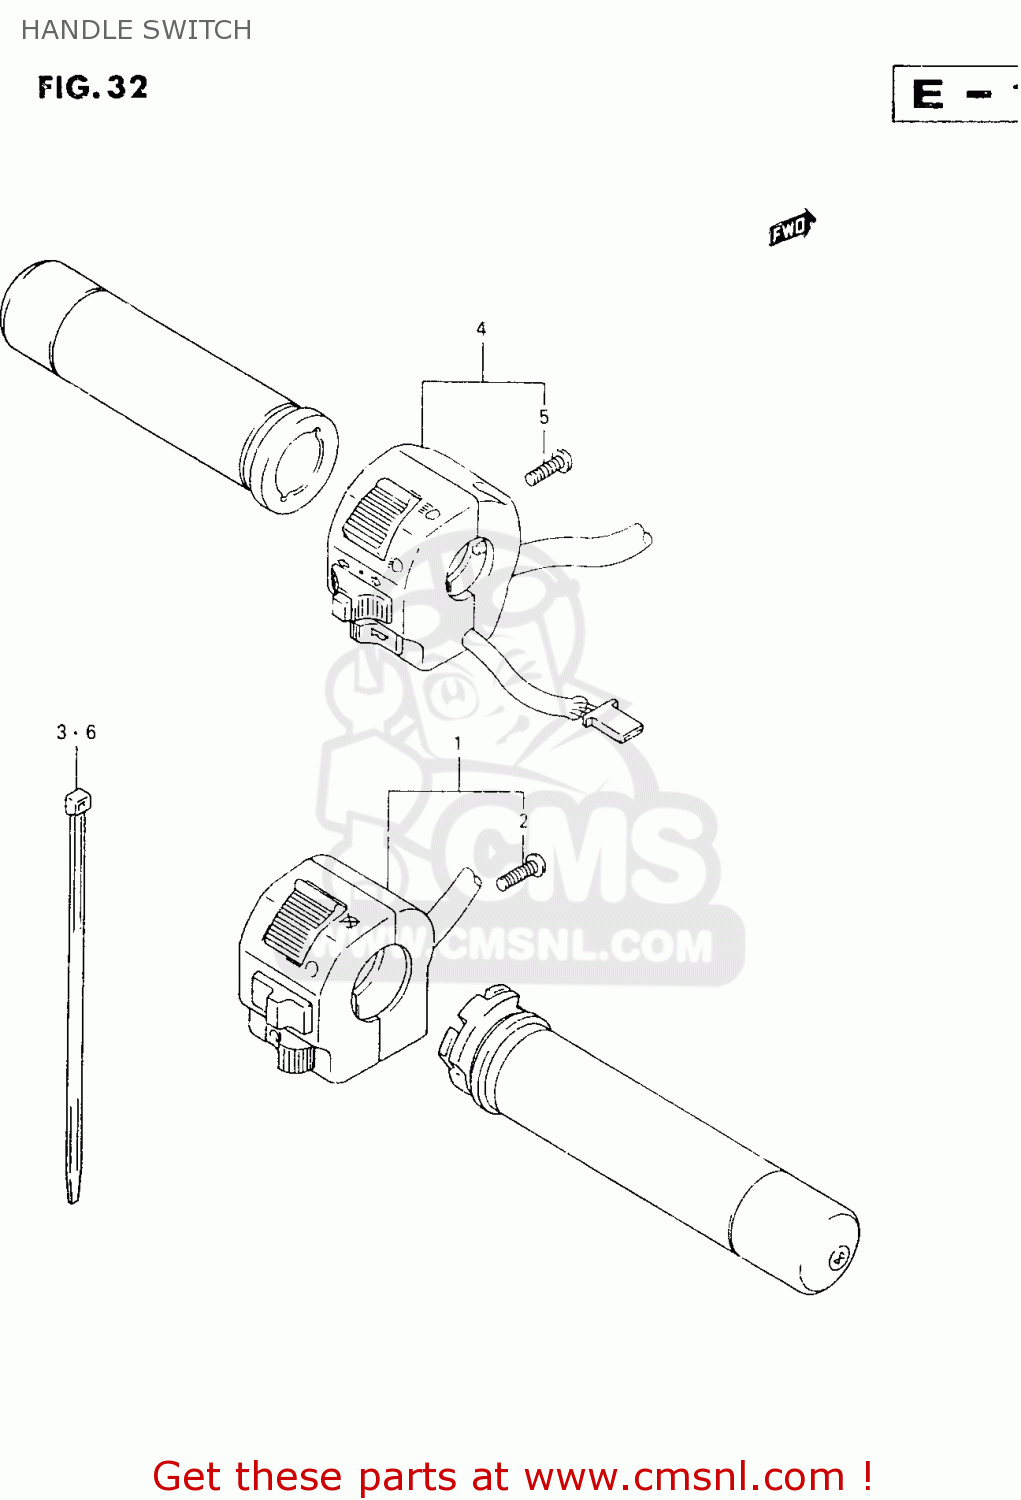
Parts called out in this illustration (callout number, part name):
1	SWITCH ASSY,HANDLE,R
2	SCREW
3	CLAMP(L:145)
4	SWITCH ASSY,HANDLE,L
5	SCREW
6	CLAMP(L:145)
